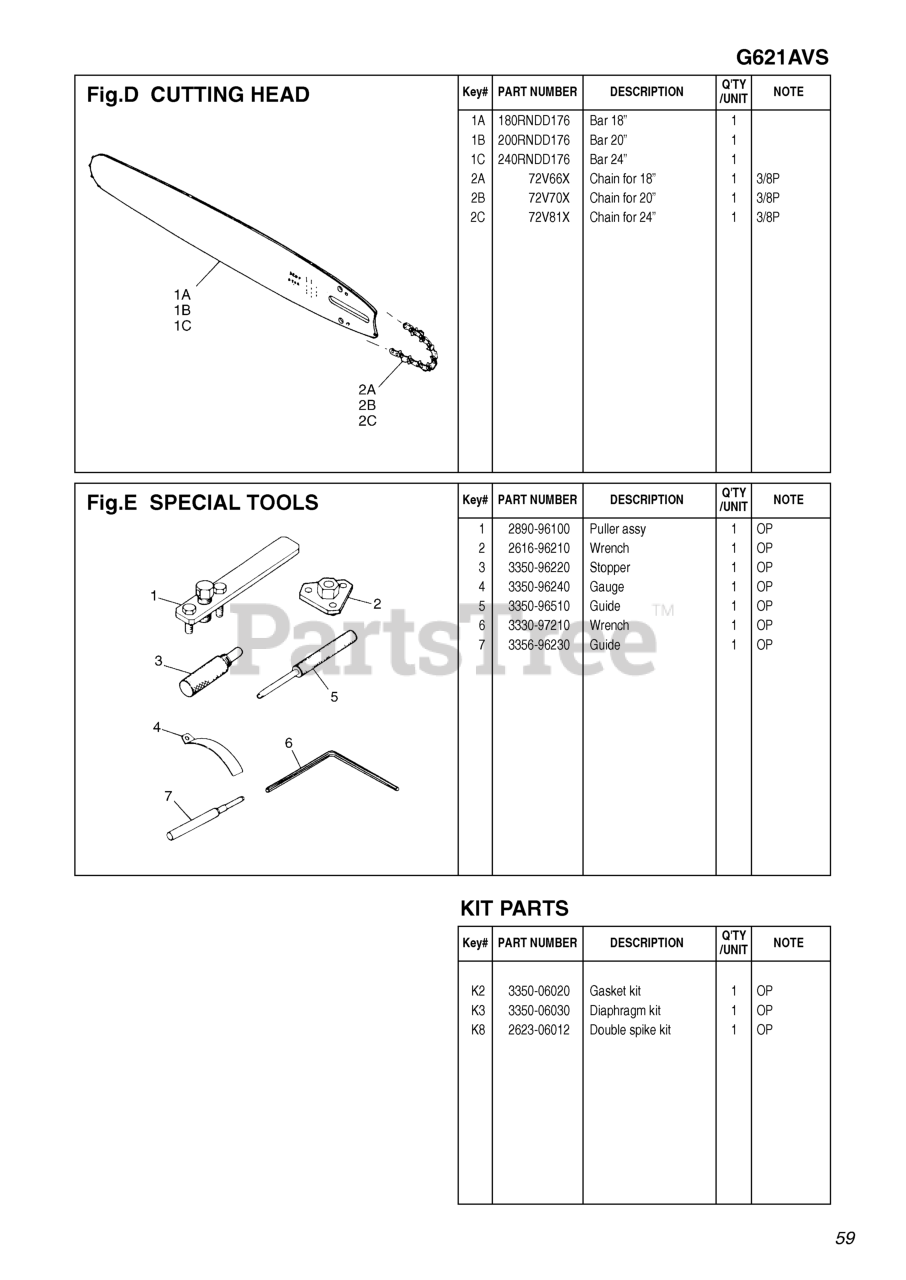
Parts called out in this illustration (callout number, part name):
1	PULLER ASSY
1A	BAR 18
1B	BAR 20
1C	BAR 24
2A	CHAIN FOR 18
2B	CHAIN FOR 20
2C	CHAIN FOR 24
3	STOPPER
7	GUIDE
NI	GASKET KIT
NI	DIAPHRAGM KIT
NI	DOUBLE SPIKE KIT
